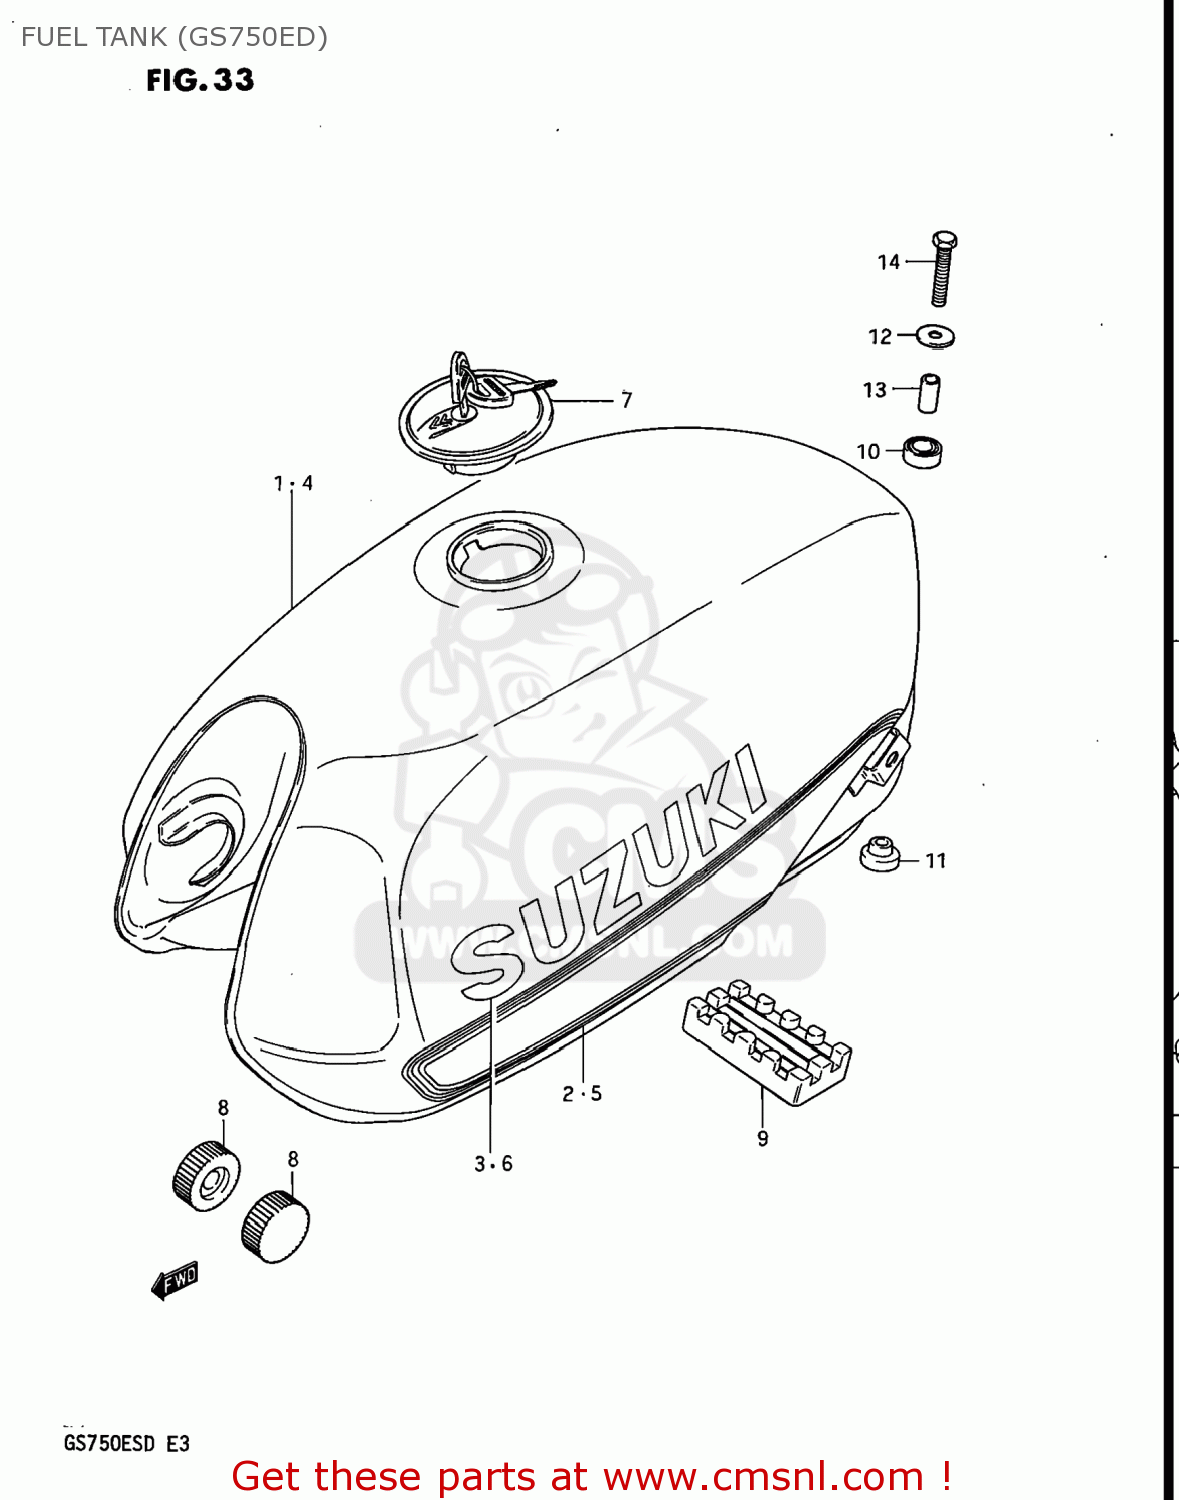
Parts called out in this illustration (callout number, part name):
1	TANK ASSEMBLY,FUEL
2	TAPE SET,FUEL TANK
3	EMBLEM,FUEL TANK
4	TANK ASSEMBLY,FUEL
5	TAPE SET,FUEL TANK
6	EMBLEM(SILVER)
7	CAP SET,FUEL TANK
8	CUSHION
9	CUSHION,FUEL TANK CTR
10	CUSHION
11	CUSHION
12	WASHER (6.5X24X1.6)
13	SPACER
14	BOLT
